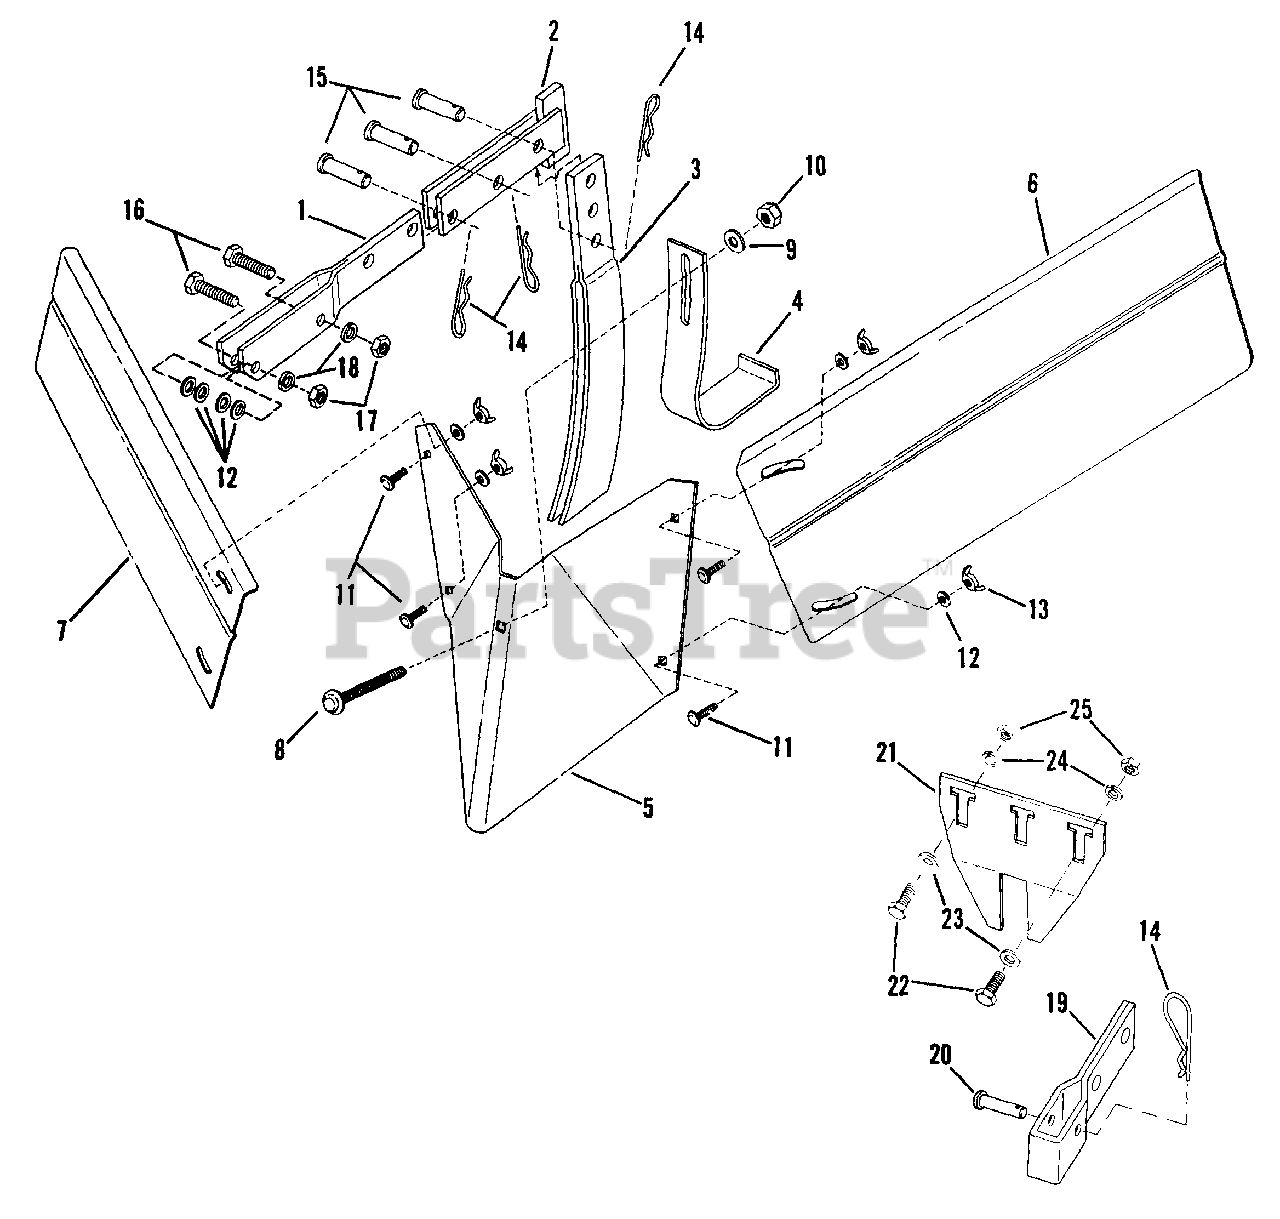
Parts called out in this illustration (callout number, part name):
1	BRACKET, Clevis
2	DRAW-BAR
3	STANDARD
4	SKID-SHOE
5	HILLER - FORROWER
6	WING, Hiller (Left Side)
7	WING, Hiller (Right Side)
8	BOLT, 1/2-13 x 3 1/2" Carriage, Grade 2
9	WASHER, 1/2' Flat
10	NUT, 1/2-13 Hex
11	BOLT, 5/16-18 x 3/4" Carriage
12	WASHER, 5/16" Flat
13	WING-NUT, 5/16-18
14	PIN, .148 x 2 5/8" Hair
15	PIN, 1/2 x 1" Clevis
16	BOLT, 5/16-18 x 1 1/2" Hex Head
17	NUT, 5/16-18 Hex
18	WASHER, 5/16 Split Lock
19	BRACKET, Mounting
20	PIN, 3/8 x 1 1/2" Clevis
21	CLEVIS, Support
22	SCREW, 3/8-16 x 3/4" Hex Head Cap
23	WASHER, 3/8" Flat
24	WASHER, 3/8 Split Lock
25	NUT, 3/8-16 Hex
